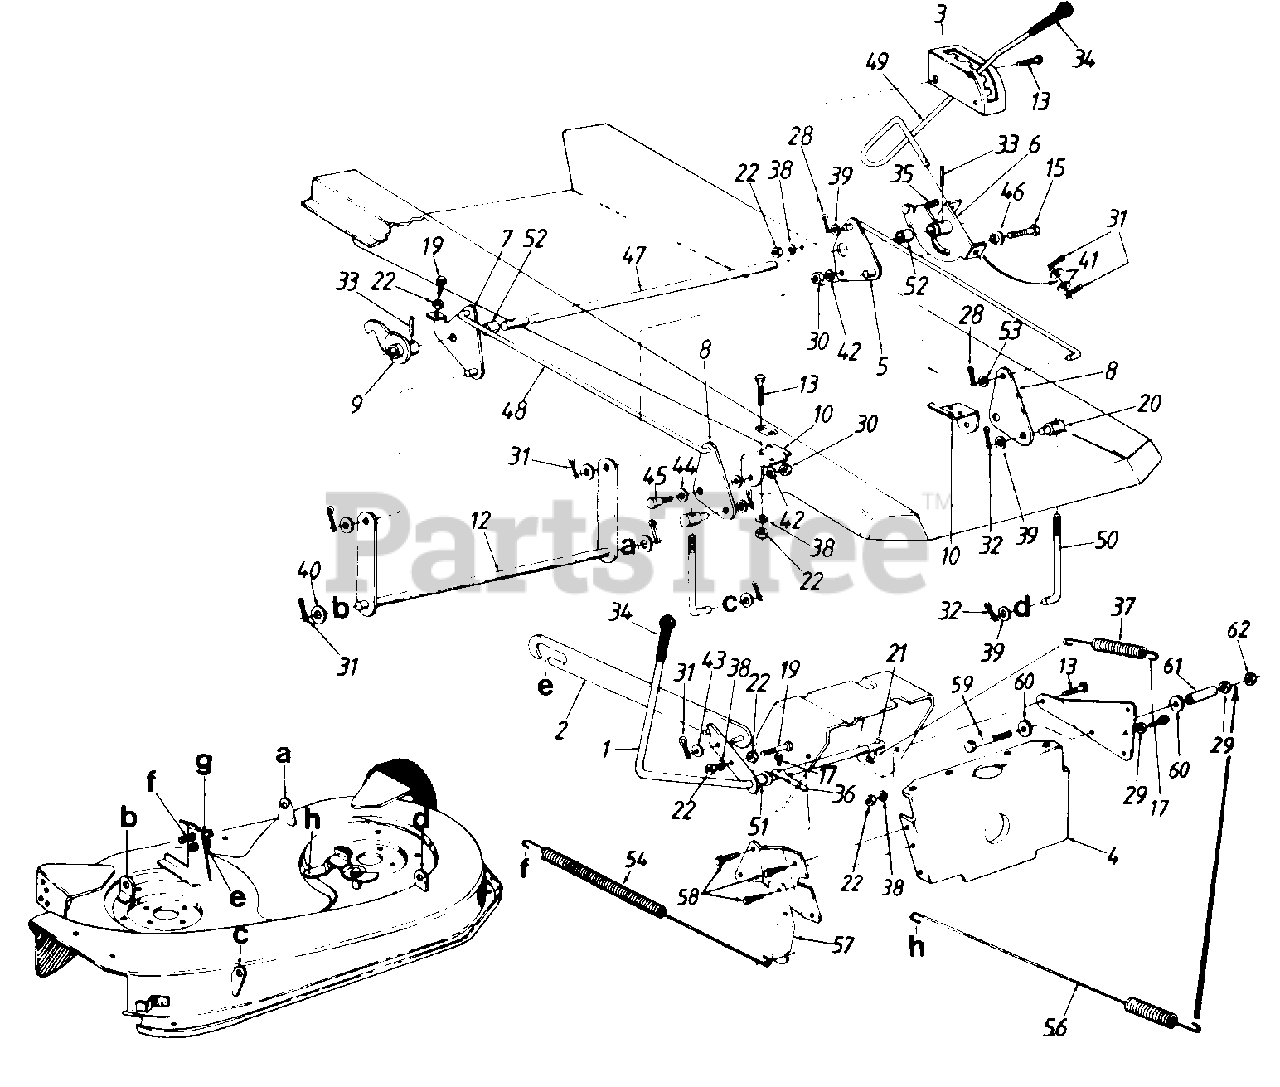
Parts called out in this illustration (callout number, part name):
1	Blade Engagement Lever Ass'y.
2	Deck Drive Control Brkt. Ass'y.
5	Deck Lift Brkt. Ass'y.
6	Deck Lift Handle Retainer Ass'y.
7	Deck Lift Brkt. Ass'y.
8	Deck Lift Bracket
9	Deck Lift Float Brkt Ass'y.
10	Deck Lift Pivot Brkt.
12	Stabilizer Shaft Ass'y.
13	Hex Bolt 5/16-18 x .75" Lg.
15	Hex Bolt 3/8-16 x 1" Lg.
17	Hex Wash. Hd. Scr. 1/4-20 x 1.5" Lg.
19	Hex Wash.-Tap Scr. 5/16-18 x 1.25" Lg.
20	Ferrule
21	Clevis Pin
22	Hex Nut 5/16-18 Thd.
28	Cotter Pin 3/32" Dia.
29	Hex Nut 1/4-20 Thd.
30	Hex Nut 3/8-16 Thd.
31	Cot-Pin 1/8" Dia. x 1" Lg.
32	Int. Cot. Pins 3/8" Dia.
33	Spring Pin Spir. 1/4" Dia.
35	Compression Spring 1.04" Lg.
36	Switch Actuator
37	Ext. Spring 5.86" Lg.
38	L-Wash 5/16" I.D.
39	Fl-Wash. .385 I.D. x .62
40	Fl-Wash. .635 I.D. x 1.12
41	Fl-Wash. .531 I.D. x .930
42	L-Wash. 3/8" I.D.
43	Fl-Wash. .385 I.D. x .87 O.D.
44	Spring Washer .530 I.D.
45	Shld. Bolt .500" Dia. x .215 Lg.
46	Shld Spacer.625" I.D.
47	Rear Hot Adj. Shaft
50	J-Bolt 5.4" Lg.
51	Spacer. 511 I.D.
52	Spacer .885 I.D.
53	Fl-Wash. 5/16" I.D.
54	Ext. Spring 22.05" Lg.
56	Ext. Spring 15.38" Lg.
57	Spring Anchor
58	Hex Wash. Hd. AB-Tap Scr. 1/4 x.62" Lg.
59	Hex Bolt 1/4-20 x 2.5" Lg.
60	Fl-Wash. .25" I.D. x .93" O.D.
61	Spacer.255" I.D.
62	Hex L-Nut 1/4-20 Thd.
